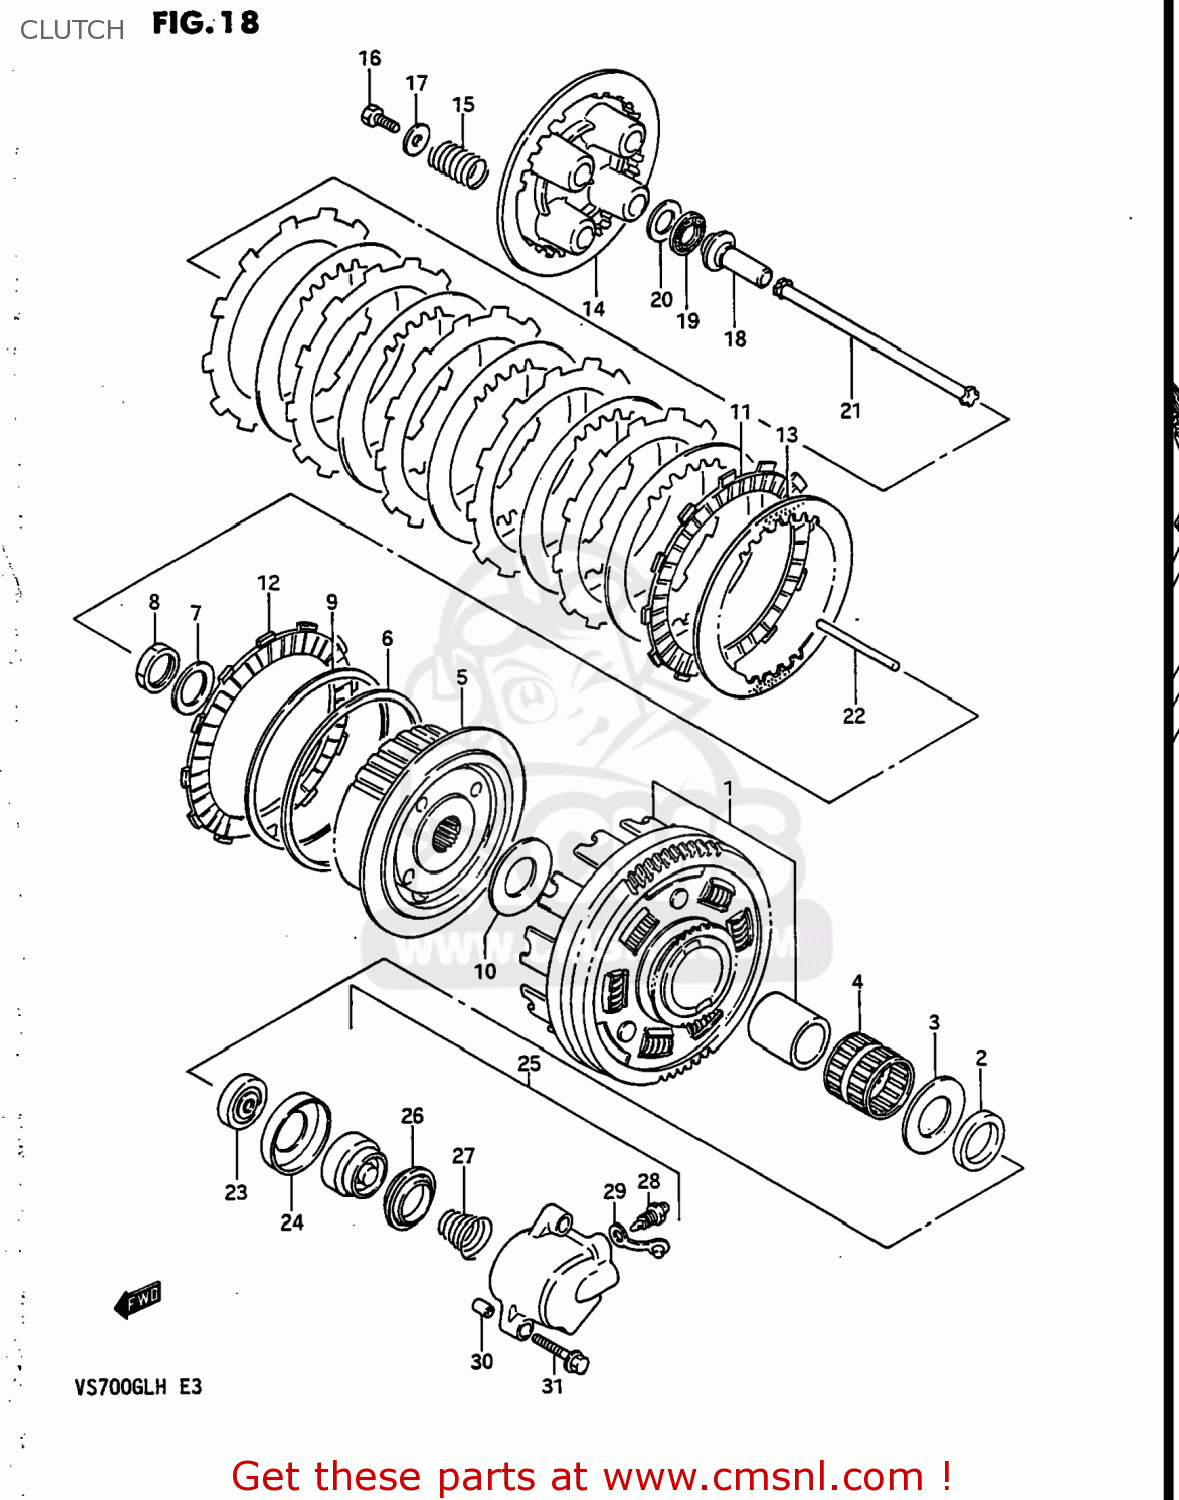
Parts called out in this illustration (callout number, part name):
1	GEAR ASSEMBLY,PRIMARY DRIVE
2	SPACER(25X38X6.5)
3	WASHER(25X50X2.5)
4	BEARING(35X40X35.8)
5	HUB COMP,CLUTCH SLEEVE
6	SEAT,WAVE WASHER(T:1.4)
7	WASHER
8	NUT
9	WASHER
10	WASHER(25X50X2.5)
11	PLATE,CLUTCH DRIVE (NAS)
12	PLATE,CLUTCH DRIVE
13	PLATE,CLUTCH DRIVEN(T:1.6) (NAS)
14	DISC,CLUTCH PRESSURE
15	SPRING
16	BOLT
17	WASHER
18	PIECE,CLUTCH PUSH
19	BEARING(15X28X2)
20	WASHER
21	ROD,CLUTCH
22	ROD,CLUTCH PUSH,L
23	SEAL,OIL(6X34X11)
24	RETAINER,CL PUSH ROD OIL SEAL
25	CYLINDER,CLUTCH RELEASE
26	CUP,CLUTCH CYLINDER
27	SPRING,CLUTCH CYLINDER
28	BLEEDER
29	CAP,BLEEDER
30	PIN
31	BOLT
